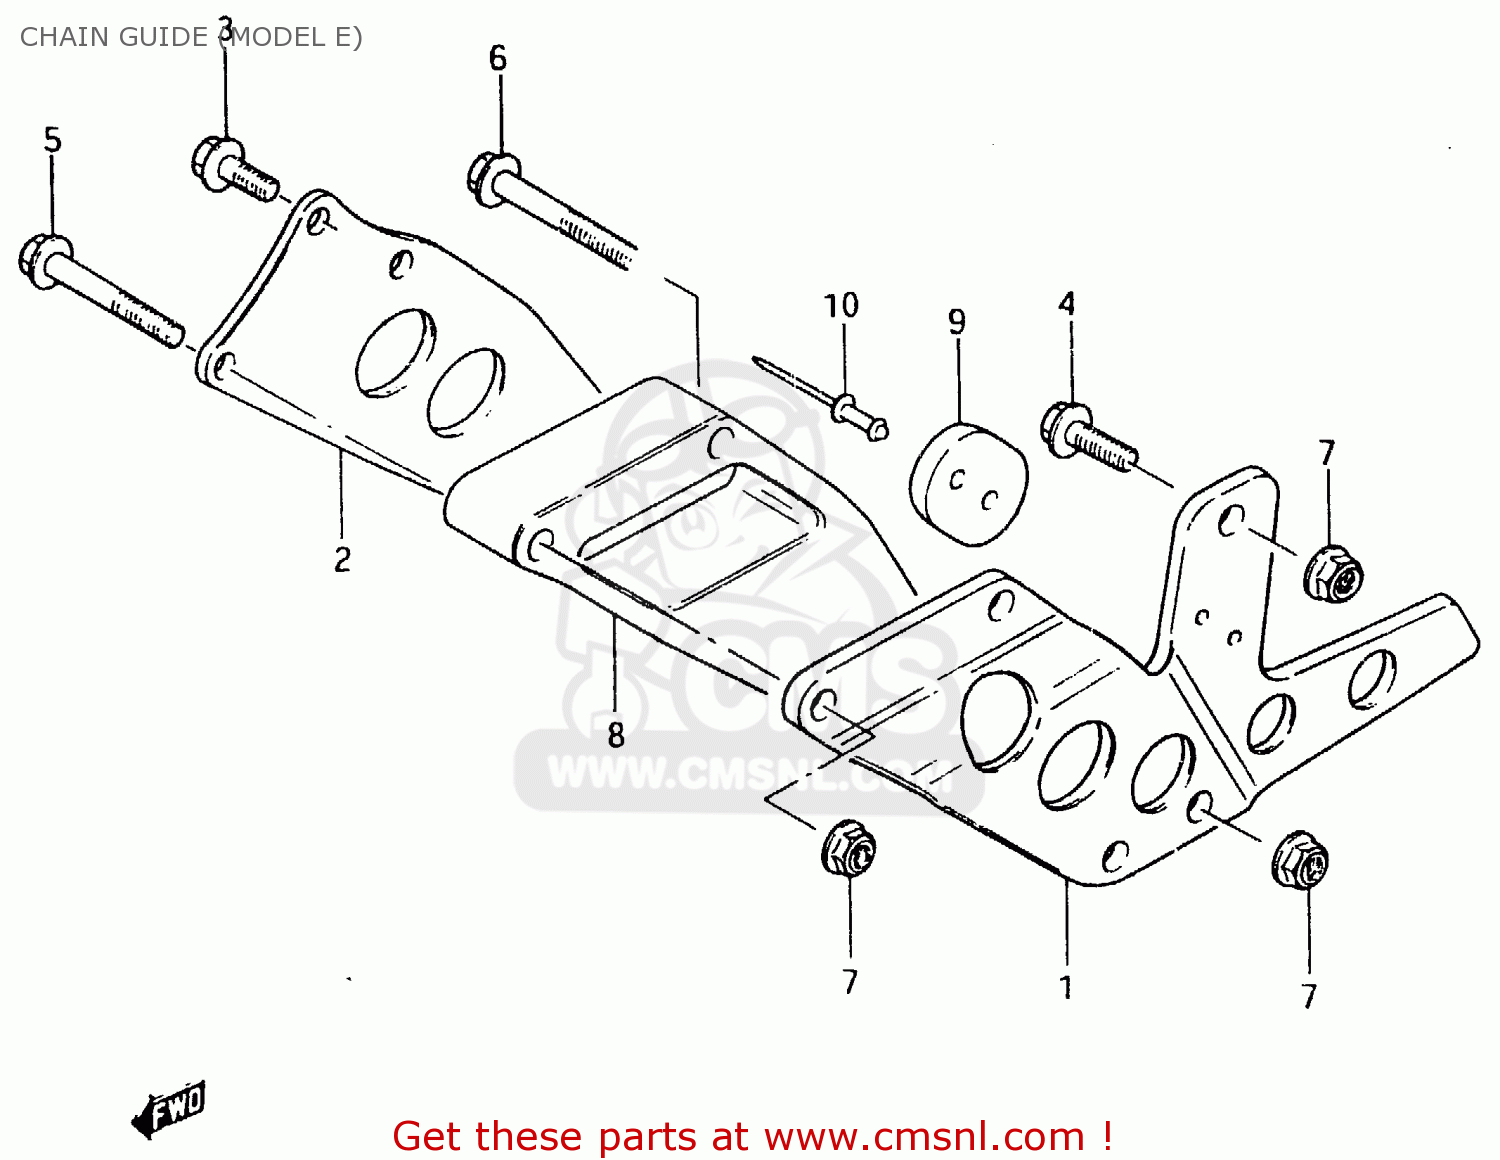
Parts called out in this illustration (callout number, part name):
1	PLATE,CHAIN GUIDE,OUTER
2	PLATE,CHAIN GUIDE,INNER
3	BOLT
4	BOLT
5	BOLT
6	BOLT,UNDER
7	NUT
8	DEFENSE,CHAIN GUIDE
9	PAD,CHAIN GUIDE
10	RIVET
